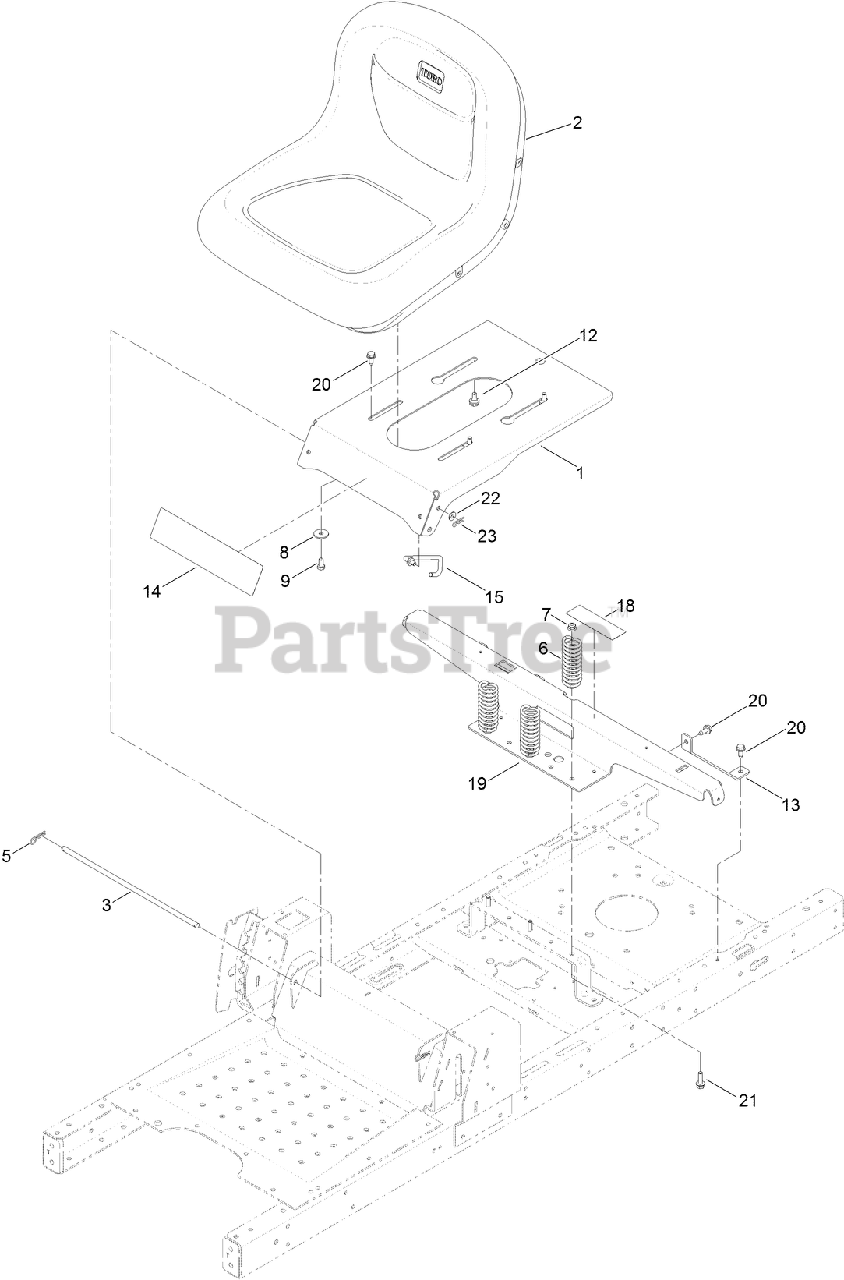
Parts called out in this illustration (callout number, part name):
1	PAN-SEAT
2	SEAT-15 INCH
3	ROD-PIVOT, NARROW
5	PIN-COTTER
6	SPRING-COMPRESSION
7	NUT-HF, NI
8	WASHER-PIVOT
9	SCREW-HH
12	BOLT-SHOULDER
13	SUPPORT-TANK, REAR
14	DECAL-TIMECUTTER
15	STOP-SEAT
18	DECAL-SERVICE, CE
19	SUPPORT-POD
20	SCREW-HWHTF
21	SCREW-HHF
22	WASHER-PLAIN
23	PIN-COTTER
